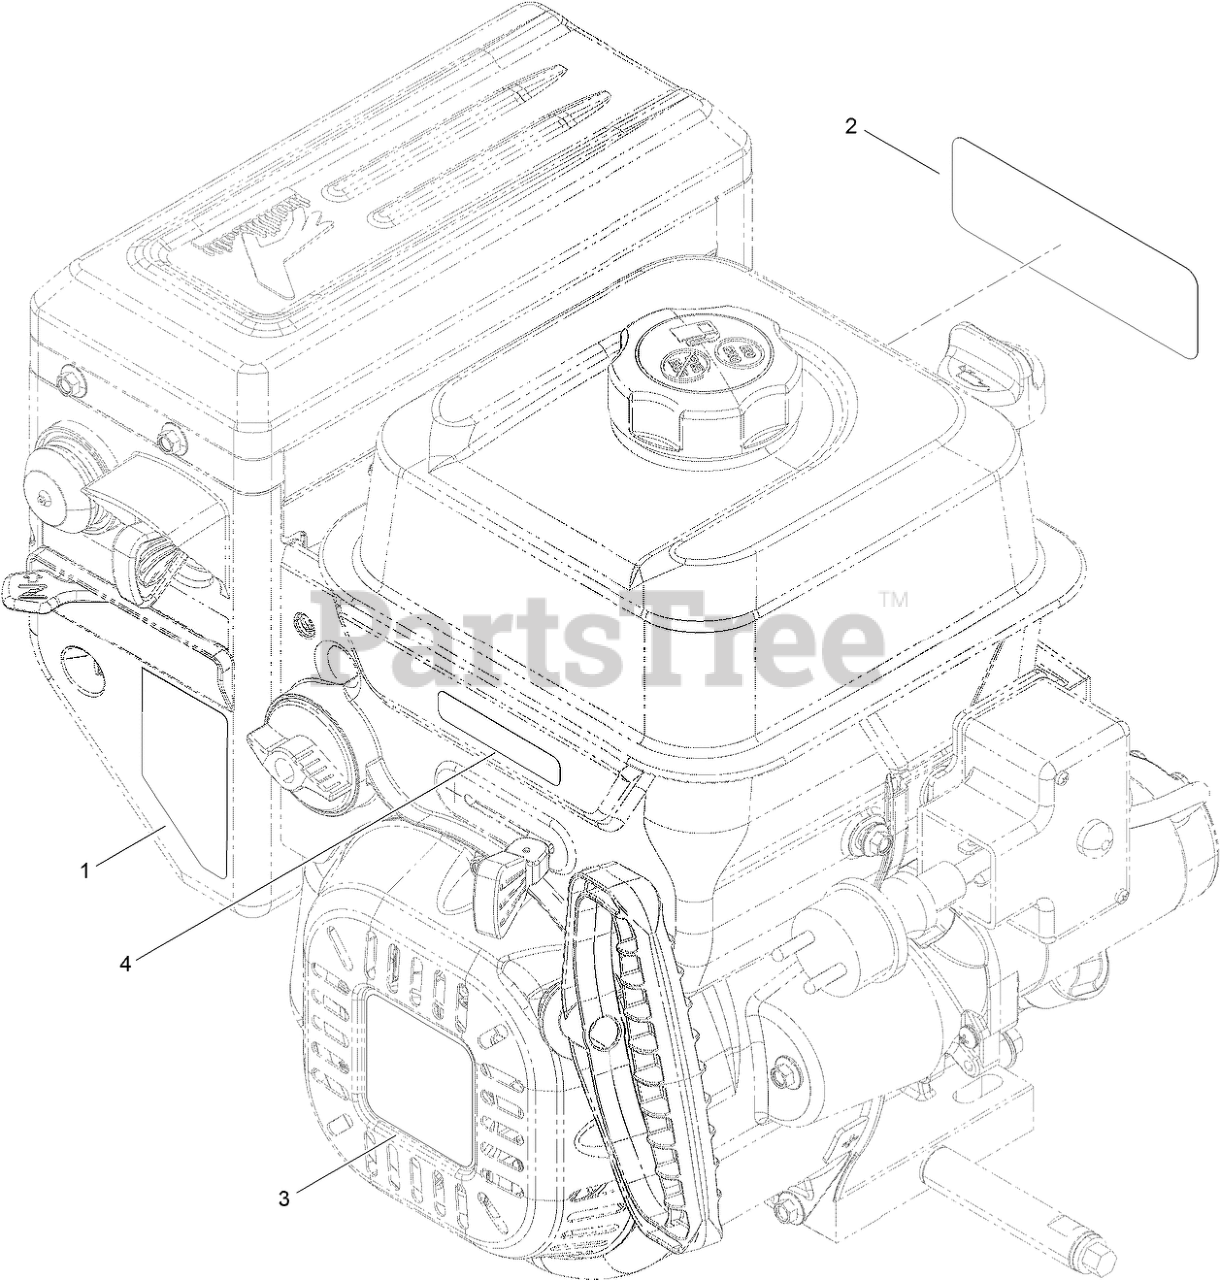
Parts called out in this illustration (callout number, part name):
1	DECAL-CONTROL, ENGINE
2	DECAL-ENGINE SERIES, G250
3	DECAL-RECOIL, G250
4	DECAL-THROTTLE
